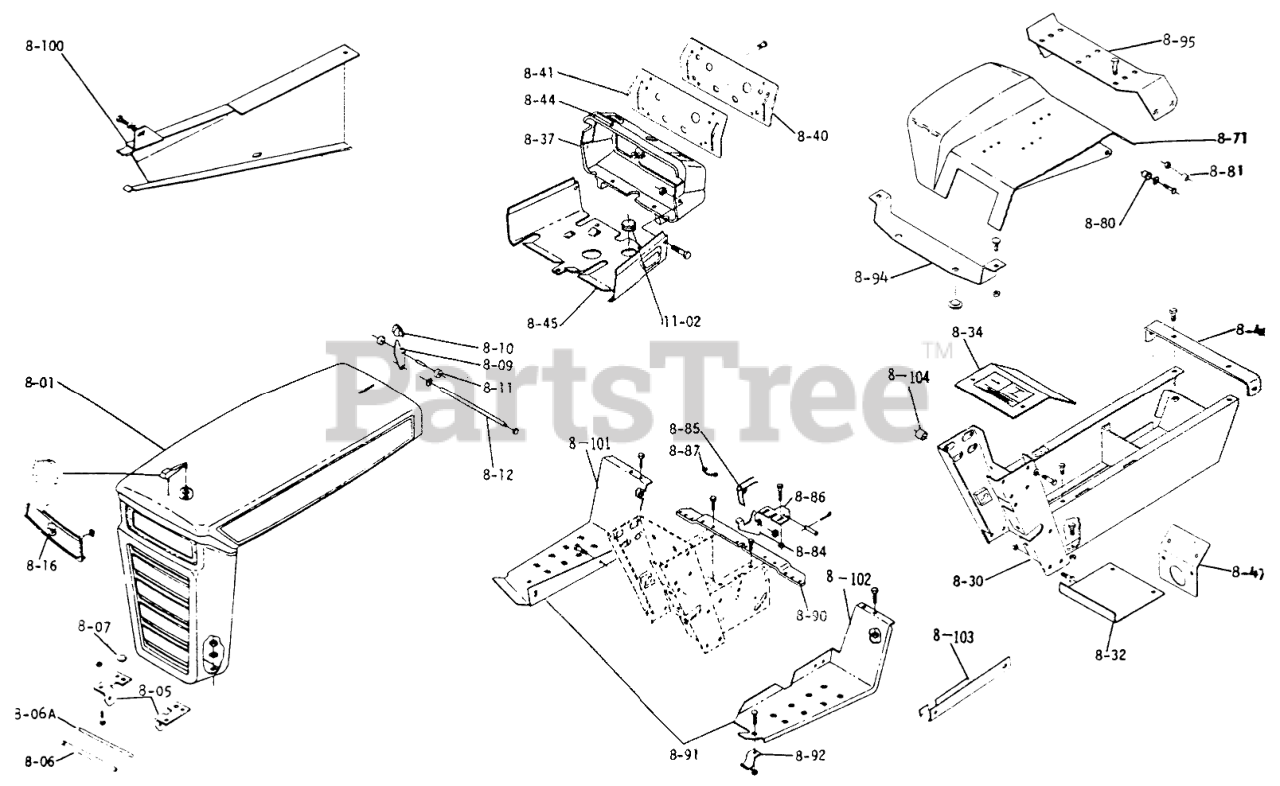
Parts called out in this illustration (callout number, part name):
8-06	GRILL PIVOT ROD
8-06A	ROD-HOOD STOP
8-07	GROMMET
8-09	LEVER HOOD LATCH
8-10	KNOB
8-15	Hood Ornament
8-16	ESCUTCHEON PLATE
8-32	Cover-Dust
8-71	Fender
8-80	BUSHING-FLANGED
8-85	Spring
8-87	Stop-Fender Latch
8-92	BRACKET
